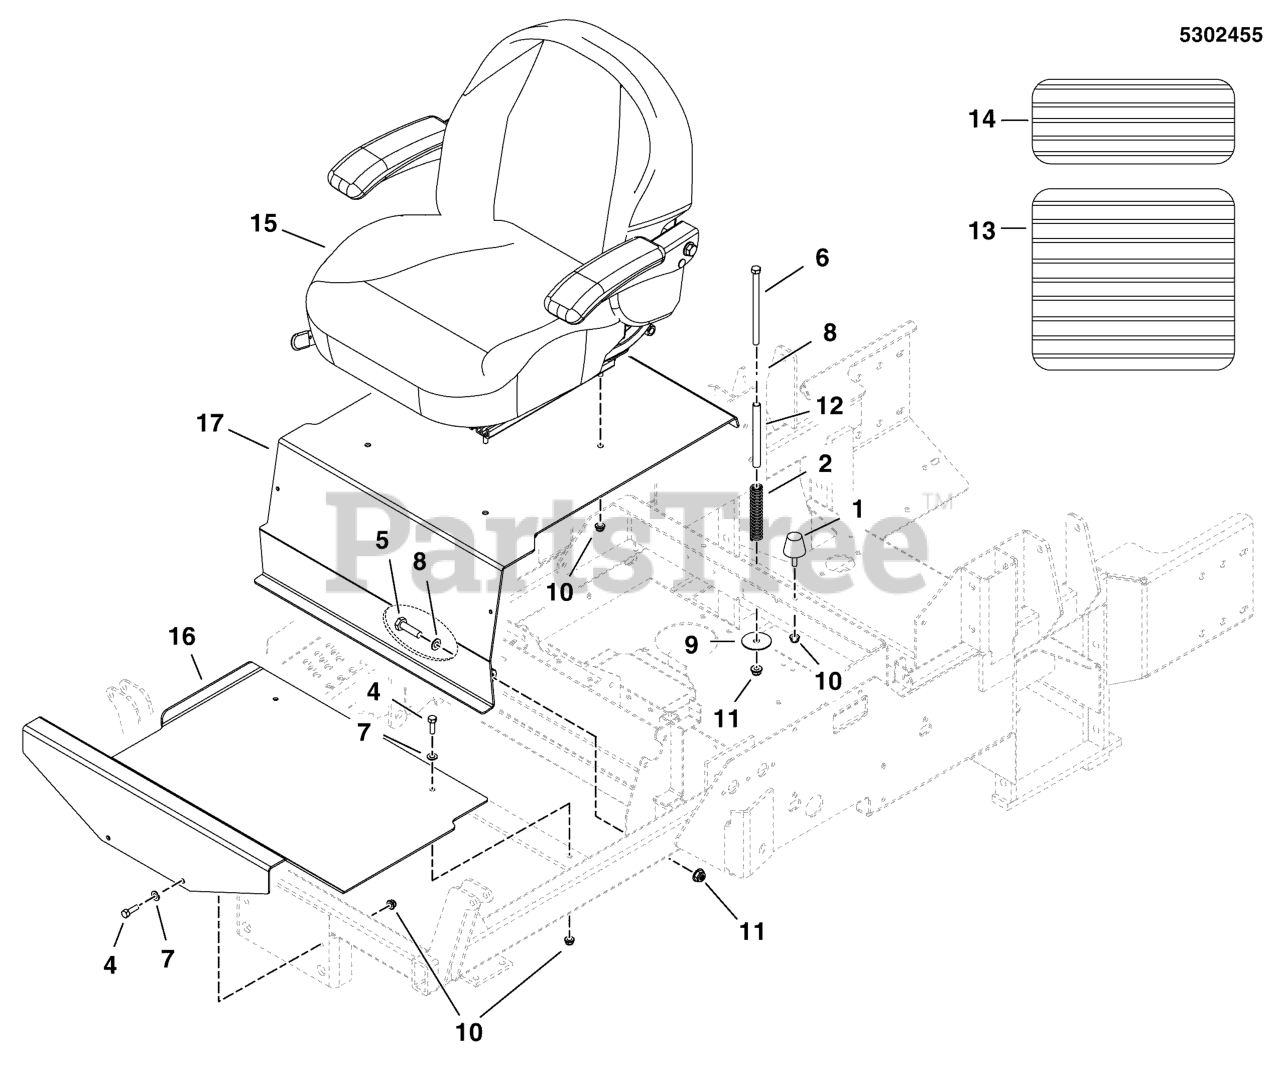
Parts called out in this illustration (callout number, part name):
1	BUMPER, RUBBER 5/16-18
2	SPRING, COMP, .835 X.105 X4.26
4	BOLT, 5/16-18 X 1 GD5 YZ
5	BOLT, 3/8-16 X 3-1/2" GD5 CZ
6	BOLT, 3/8-16 X 6" GD5 CZ
7	WASHER, 5/16" SAE
8	WASHER, 3/8 SAE
9	WASHER, .39 X 2.00 X X .14
10	NUT, 5/16-18 HEX NYLOCK FLANGE
11	NUT, 3/8-16 HEX NYLOCK FLANGE
12	SPACER, .38 X .50 X 5.06
13	SAFETY WALK, FLOOR PLATE, 17.13 X 11.50
14	SAFETY WALK, FLOOR REST, 17.13 X 6.00
15	SEAT, 1110EVC, COMPANION
15	SEAT, IS3100Z / IS5100Z
16	PLATE, FLOOR DETAIL IS5100Z - RED
17	WELD, SEAT PLATE IS5100Z - RED
